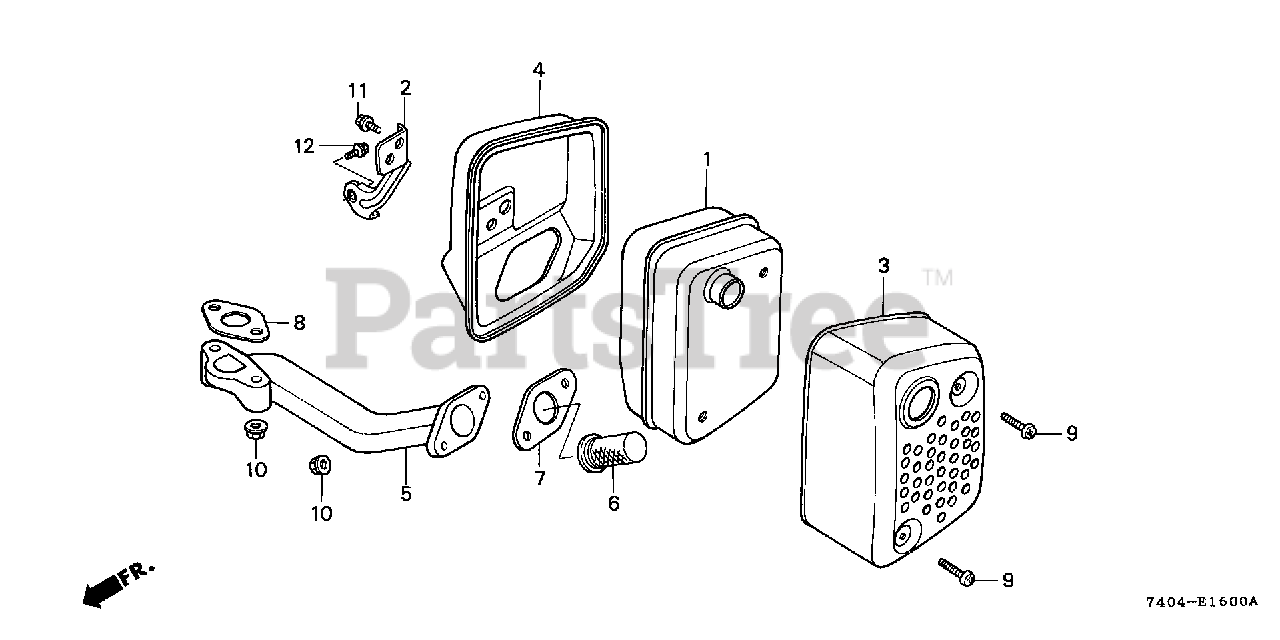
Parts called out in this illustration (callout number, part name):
2	STAY, MUFFLER
3	PROTECTOR A, MUFFLER
4	PROTECTOR B, MUFFLER
6	ARRESTER, SPARK
7	GASKET B, MUFFLER
8	GASKET, MUFFLER
9	SCREW, PAN (6X6)
10	NUT, FLANGE (6MM)
11	BOLT, FLANGE (6X10)
